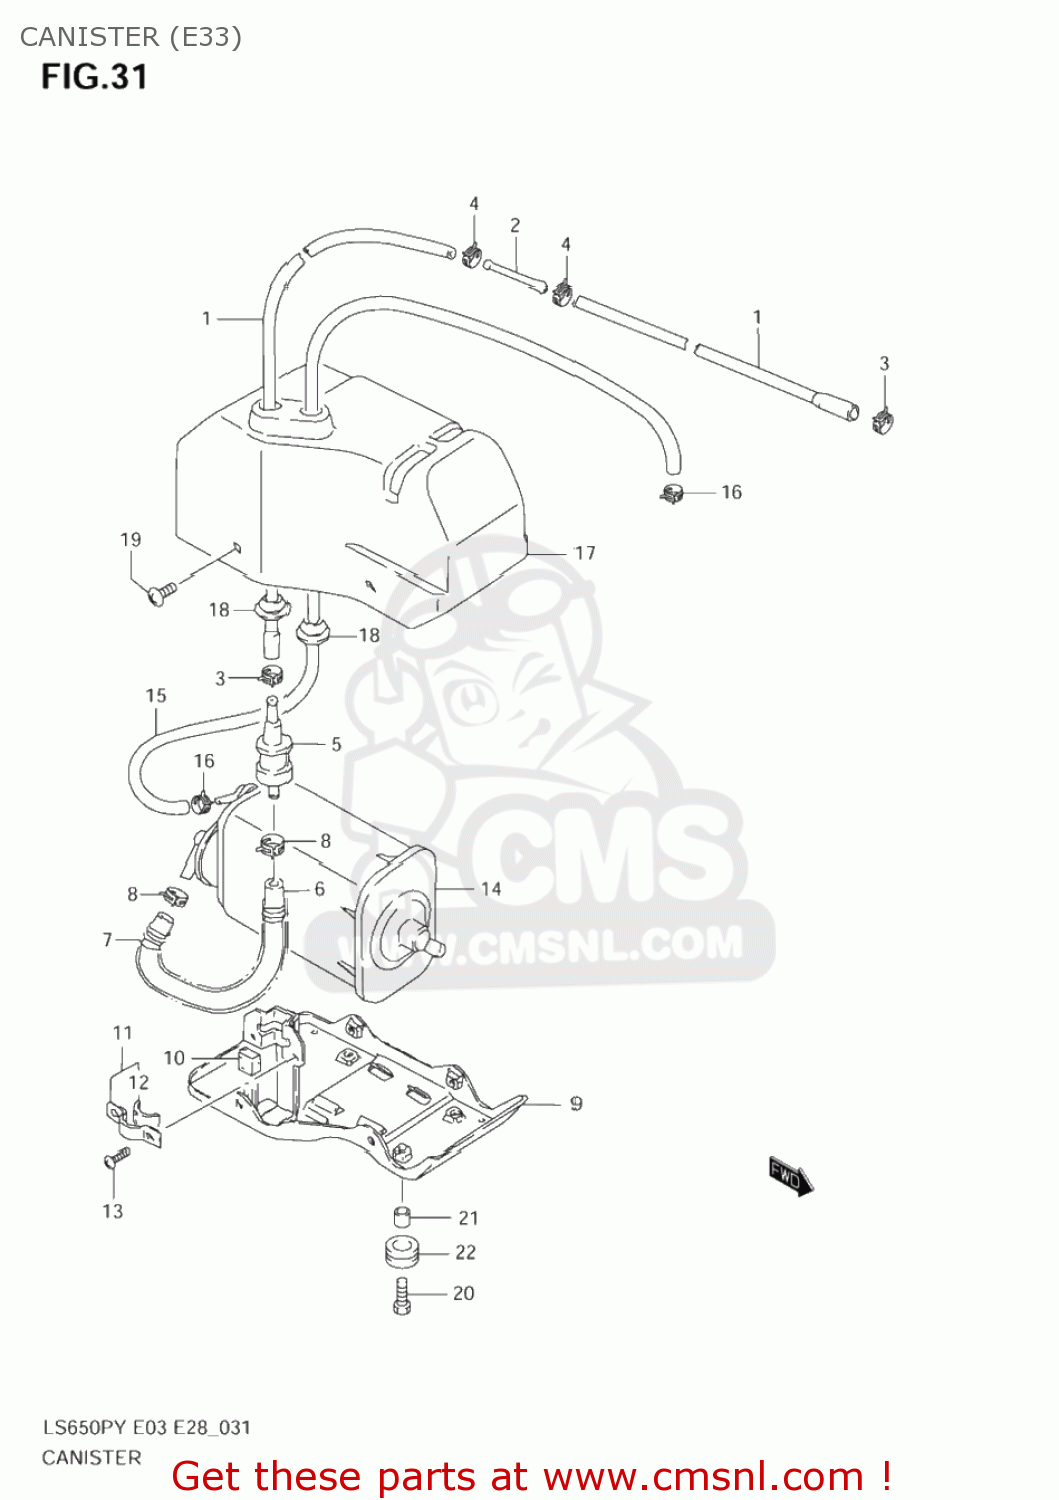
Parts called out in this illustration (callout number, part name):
1	HOSE,PURGE NO.1
2	JOINT
3	CLIP
4	CLIP
5	VALVE,FUEL TANK BREATHER
6	HOSE
7	SPRING
8	CLIP
9	PLATE,CSTR FITING
10	CUSHION
11	PLATE,FUEL TANK BREATHER NO.2
12	CUSHION
13	SCREW
14	CANISTER ASSY,CHARCOAL
15	HOSE,PURGE NO.1
16	CLIP
17	COVER,CANISTER
18	GROMMET
19	SCREW 6X10
20	BOLT(6X16)
21	SPACER
22	CUSHION
